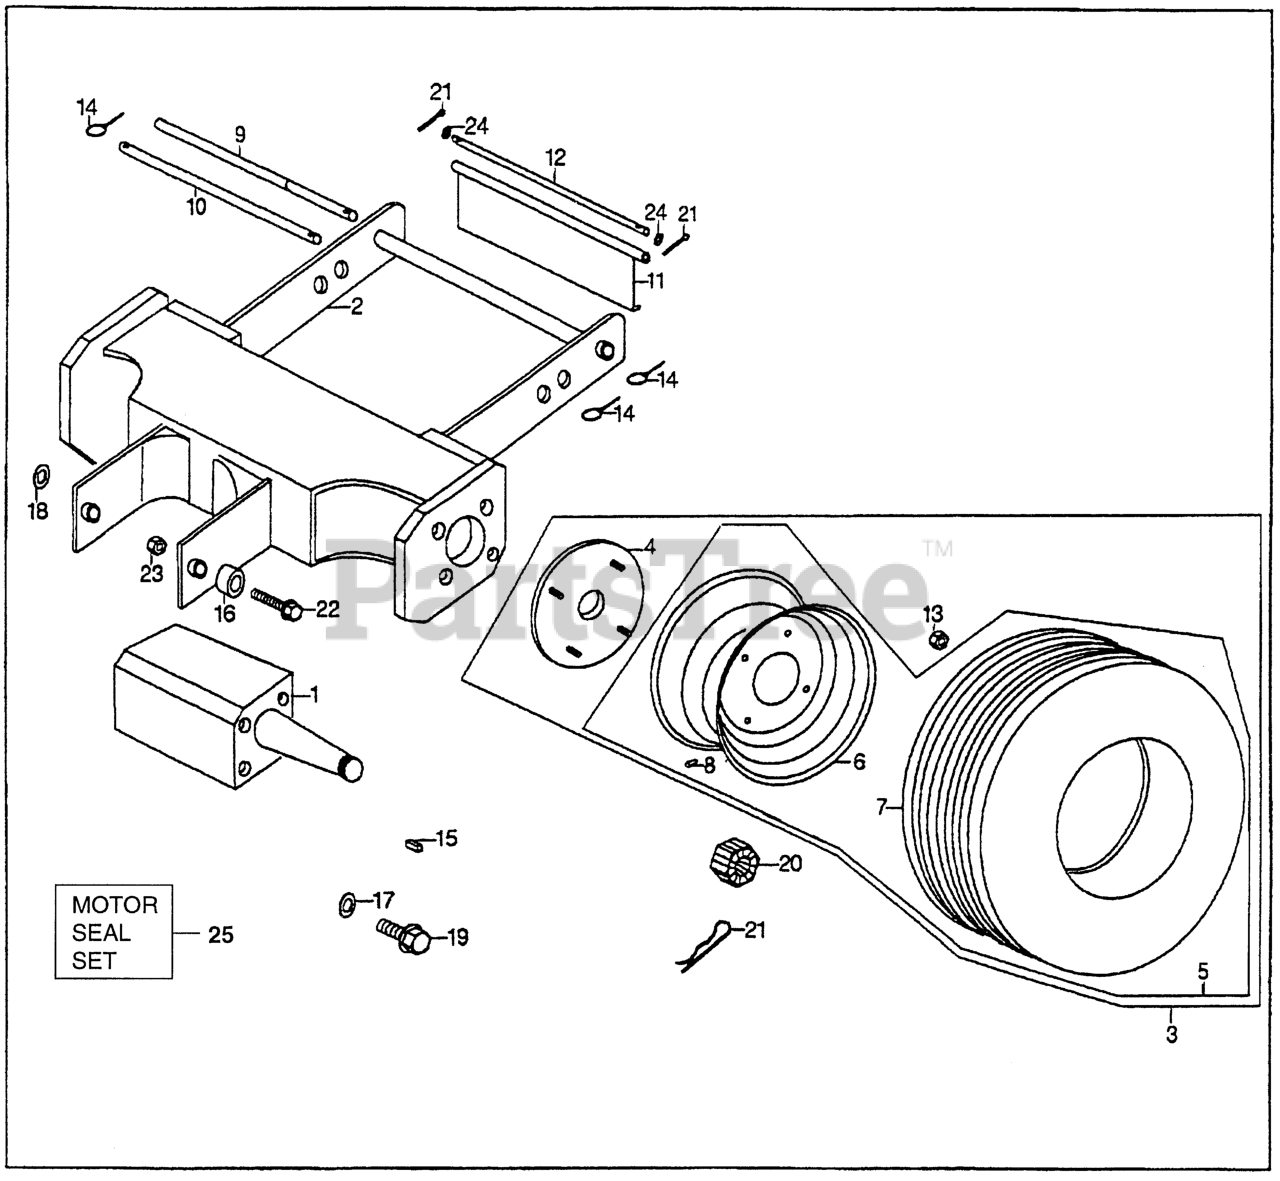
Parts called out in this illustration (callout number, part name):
1	MOTOR ASSY., HYDRAULIC
3	WHEEL ASSY., TRACTION
4	HUB, WHEEL
5	WHEEL ASSY., RR.
6	WHEEL, RR.
7	TIRE, RR.
8	VALVE, RIM
9	BAR, HEIGHT
10	SHAFT, HEIGHT (NOT AVAILABLE)
11	SHIELD, RR. (NOT AVAILABLE)
12	ROD, RR. SHIELD
13	LUG NUT, HEX. (1/2"-20)
14	QUICK CLIP
15	KEY, SQUARE (3/16"X3/16"X3/4")
16	BUSHING, AXLE
20	NUT, STRAIGHT SLOT (3/4"-24)
25	SEAL SET, MOTOR (WHITE)
